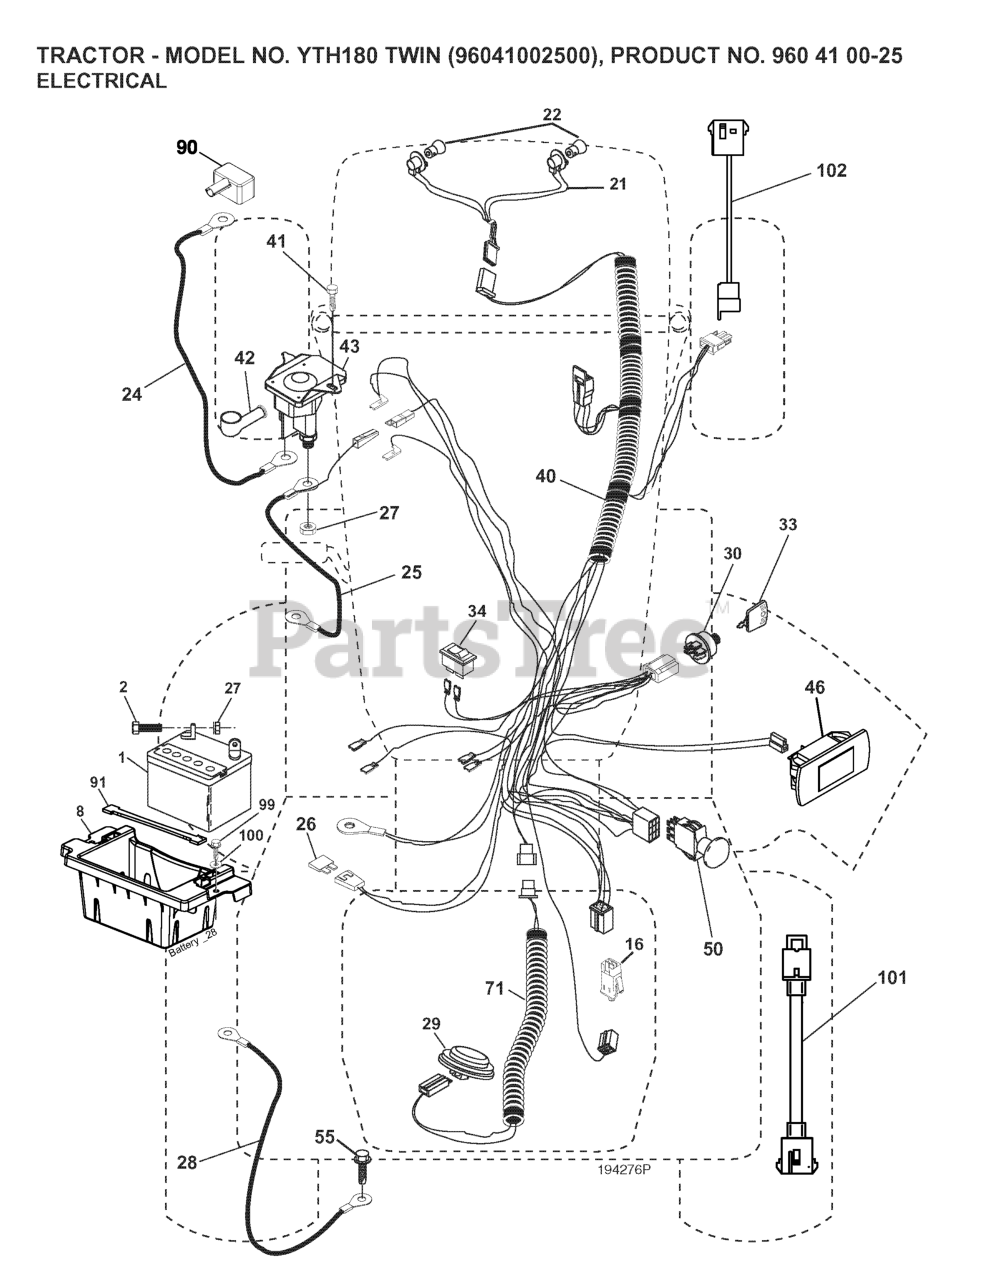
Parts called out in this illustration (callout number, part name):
1	BATTERY 12V .35 AMP
2	BOLT.HEX.1/4.X.3/4.DICHROMATE
8	BOX.BATTERY.MOUNT.FRONT.LT
16	SWITCH INTERLOOK PUSH-IN
21	HARNESS ASSY LIGHT
24	CABLE.BATT.POS.WIRE.TG.DA SOL
25	CABLE.START.RED.17.5".
26	FUSE 20AMP
27	NUT
28	CABLE GROUND 6 GA 21" 90T BLK
29	SWITCH.SEAT.DELTA.OPC.
30	SWITCH.IGN.DELTA.W.LGH.ROS
33	KEY MLD GEN DELTA
40	HARNESS.IGN.DASH.HUQ/P
41	SCREW
42	TERMINAL COVER
43	SOLENOID.W/BRASS.PLUNGER
46	RP.GUAGE.SRVCMNDR.HRMTR.
50	RP.PTO.SWITCH.8 TERMINAL.BLACK
55	SCREW 5/16"
71	HARNESS-CHASSIS SUB
90	COVER.TERMINAL.BATTERY
91	STRAP.BATTERY.MOUNT.FRONT(2 2)
99	SCREW HEXWSHR 1/4-20X3/4
101	PIGTAIL.MATNLK.NEW.HAR
102	HARNESS PIGTAIL PCH TEX ROS
